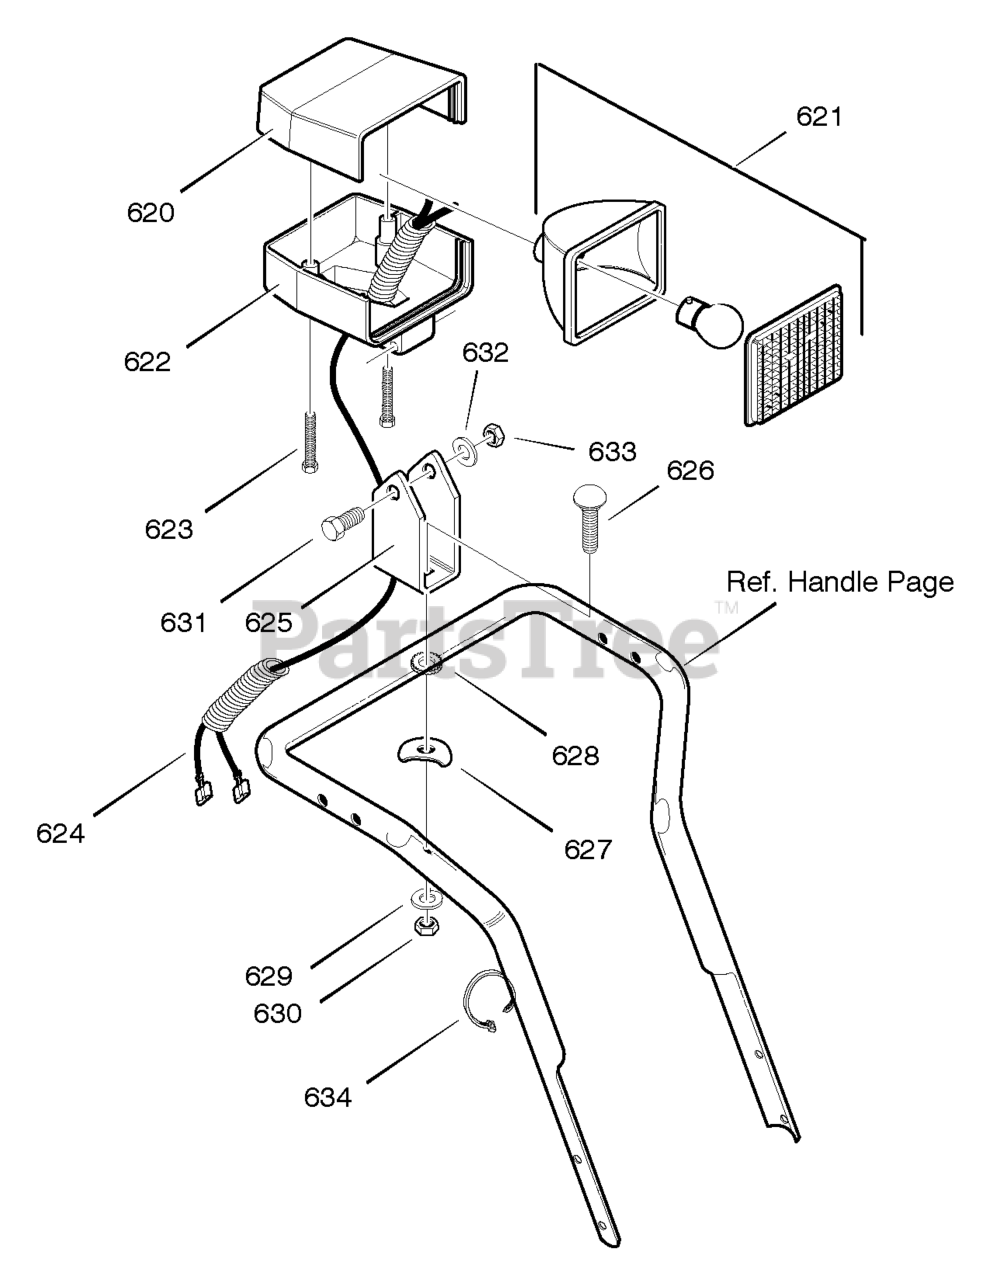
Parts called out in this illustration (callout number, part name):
620	HOUSING, HEADLIGHT UPPER
621	HEADLIGHT ASSEMBLY *
622	HOUSING, HEADLIGHT LOWER
623	SCREW, #8X1.75
624	WIRING HARNESS, HALOGEN
625	BRACKET, HEADLIGHT
626	BOLT, CARRIAGE - 5/16-18X2.00
627	WASHER, SADDLE
628	WASHER, EXLK .32X.60X.040
629	WASHER, SPTLK .31X.58X.08
630	NUT, 5/16-18 REGHEX
631	SCREW, 5/16-18 x 2.00
632	WASHER, SPTLK
633	NUT, 5/16-18 REGHEX
634	TIE, CABLE
